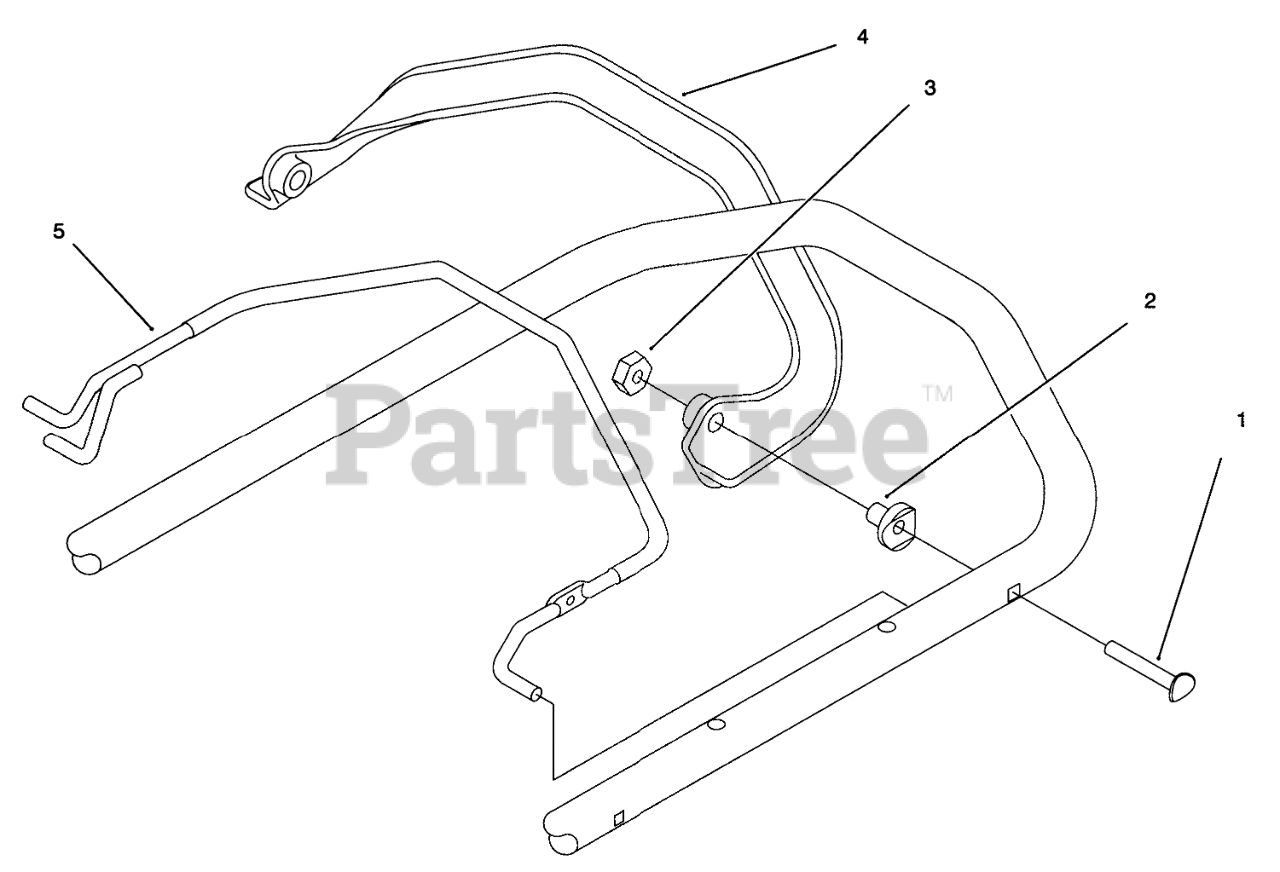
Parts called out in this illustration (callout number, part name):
1	SCREW-HANDLE
2	SPACER-SUPPORT
3	NUT-LOCK NI
4	BAIL - TRACTION
5	Bail-Brake
